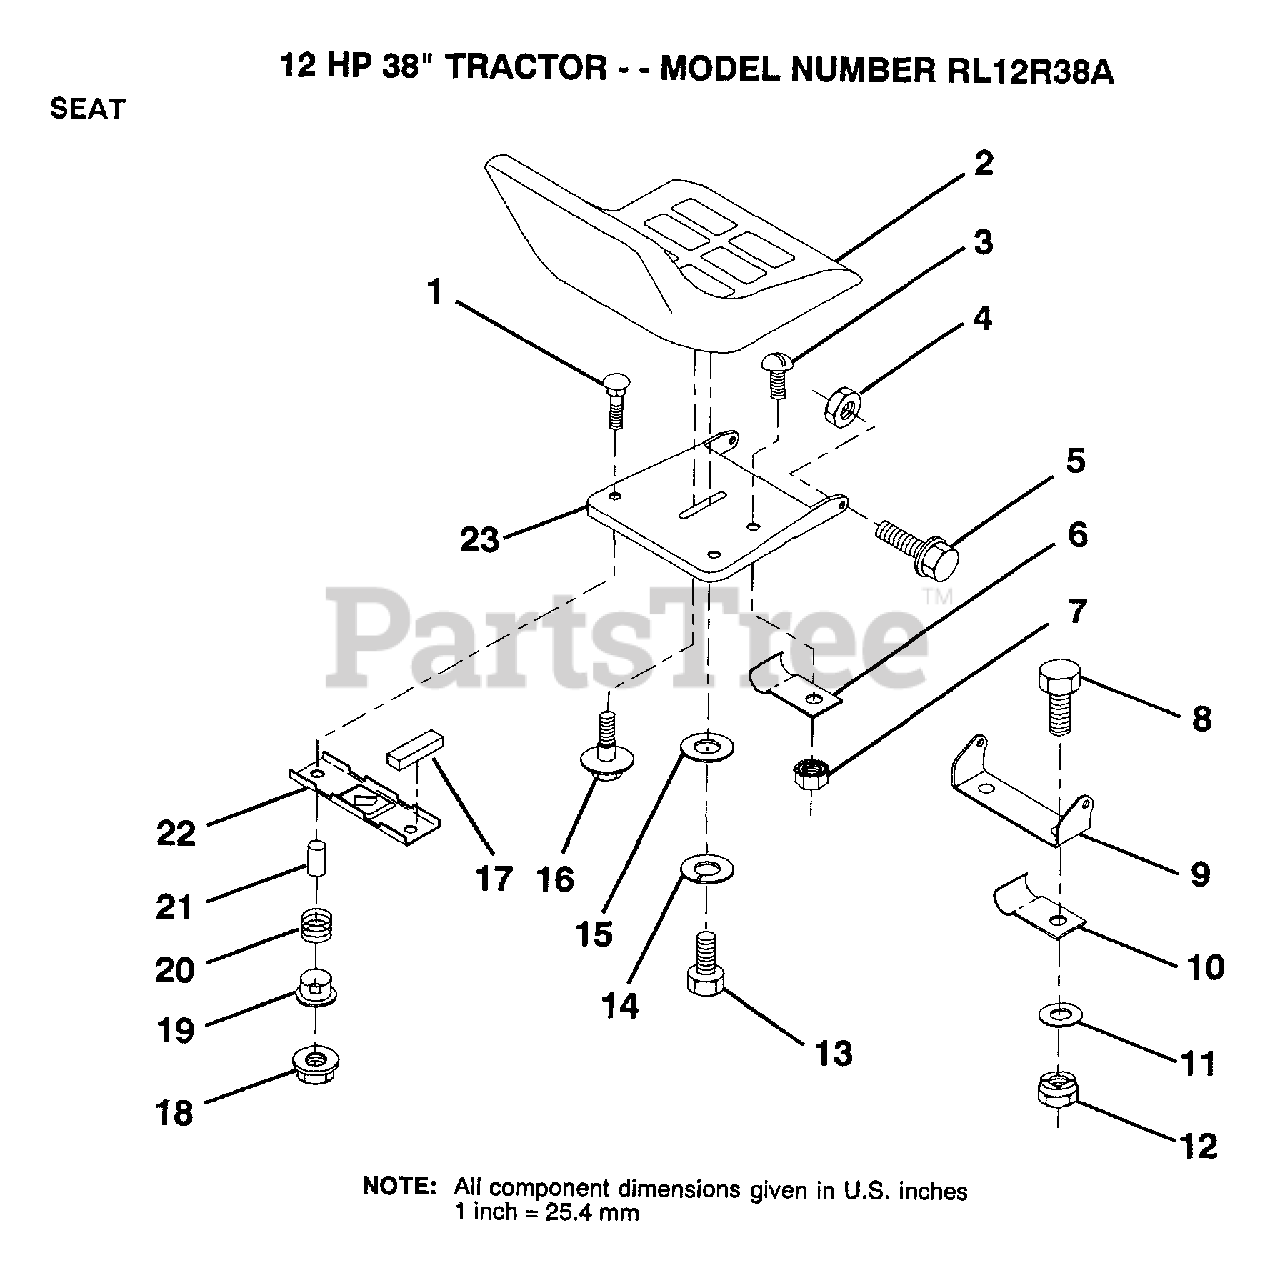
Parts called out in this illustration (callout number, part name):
7	"NUT,KEPS"
10	"CLIP,INSULATOR"
11	WASHER
13	BOLT
14	LOCKWASHER
15	WASHER
16	"BOLT,SHOULDER"
17	STRIP FORM
19	BUSHING
20	SPRING
21	SPACER SPLIT
22	BRKT SWITCH
